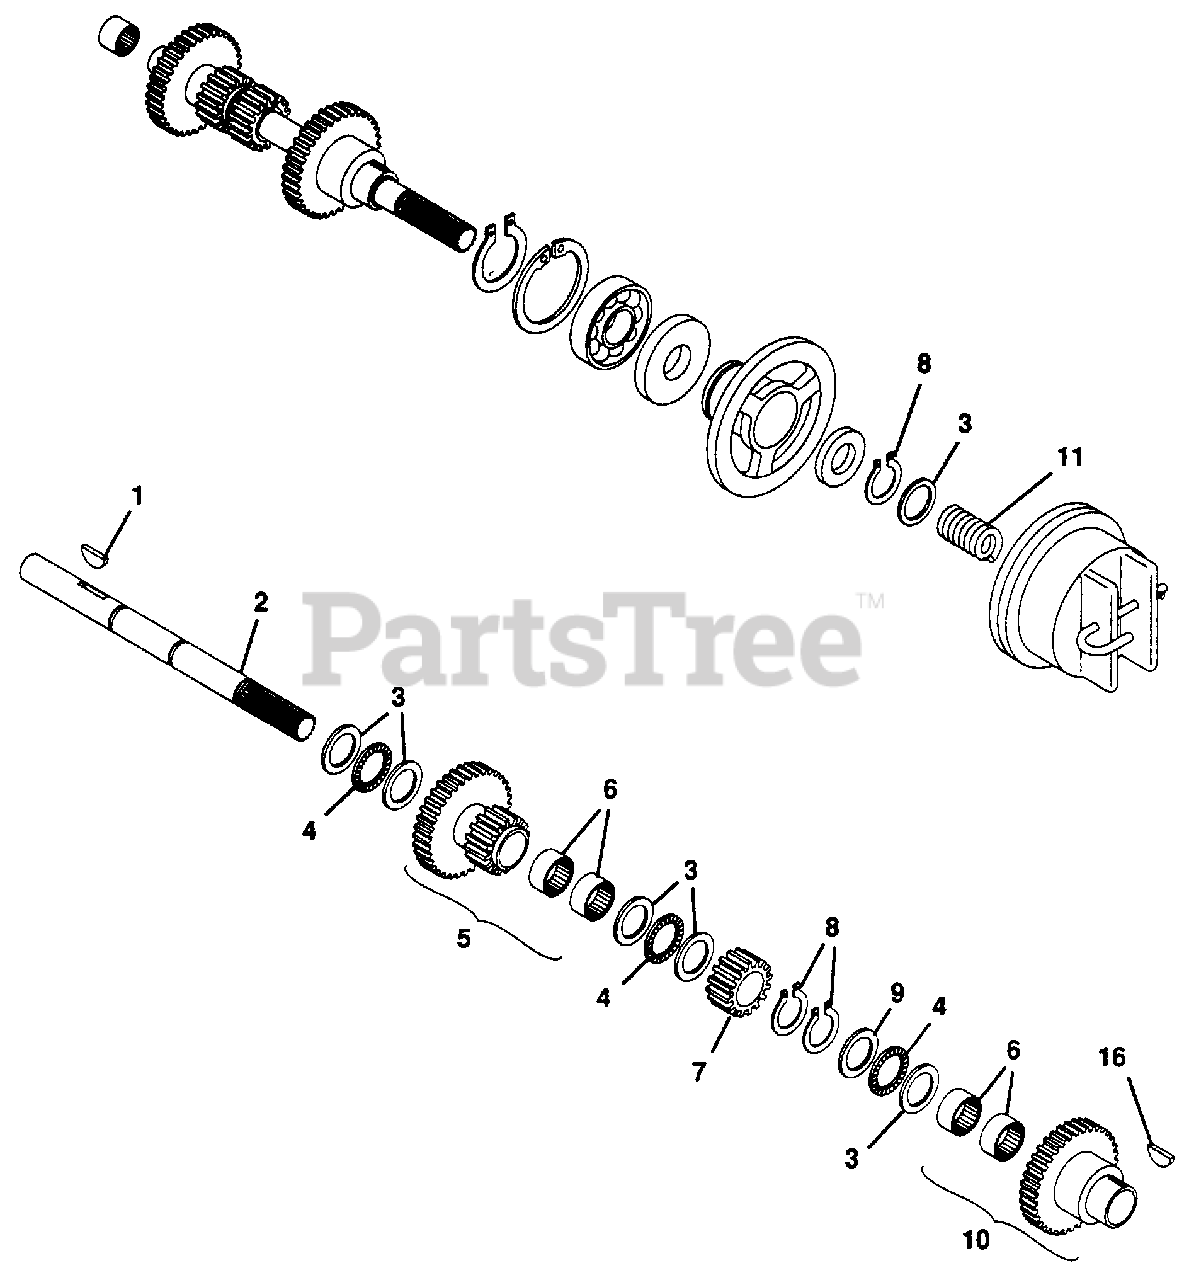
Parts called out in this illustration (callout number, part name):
1	KEY, WOODRUFF .188X.625 HRD #61
2	SHAFT, SPLINED REV CLUTCH
3	RACE, BRG THRUST .752X1.240X.030
4	BRG, NEEDLE THRUST .752X1.24X.078
5	GEAR, IDLER ASSEMBLY
6	BEARING, NEEDLE .75X1X.50
7	GEAR, 10 DP 16 TEETH X .750 STD.
8	RING, RETAINING .750 SHAFT
9	RACE, .060 BEARING THRUST
10	ASSEMBLY, REVERSE GEAR AND BRG
11	SPRING, COMP. 1.0X.80X36 LB/IN
